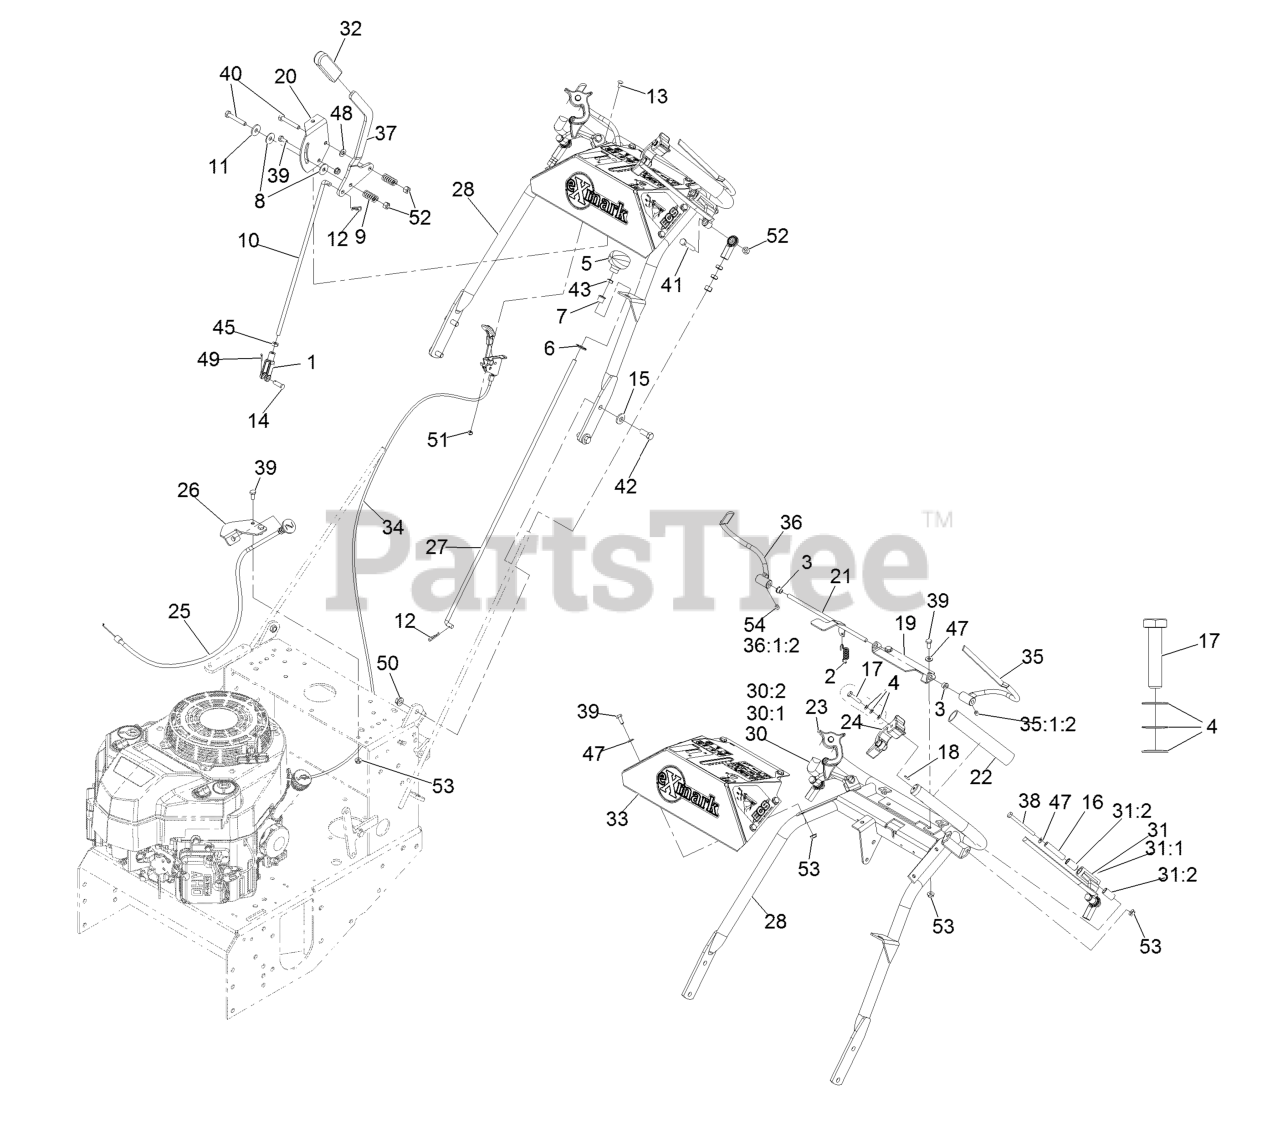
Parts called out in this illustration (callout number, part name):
1	Yoke-Adjustable
2	Spring-Extension
3	Bushing-Nylon
4	Washer-Spring Disc 1/4
5	Knob-Push / Pull
6	Nut-Push 1/2
7	Bearing-Nylon
8	Washer-Friction
9	Spring-Compression
10	Rod-Control, Speed
11	Washer-Friction Disc
12	Hairpin-Cotter
13	Bolt-Carriage #10-24 X 1/2
14	Pin-Clevis 5/16 X 1 49/64
15	Washer-Spring Disc 3/8
16	Bushing-Lever, Drive
17	Screw-HH 1/4-20 X 1 1/8 W/Nylon
18	Pin-Spring
19	Bracket, Opc Axle
20	Bracket,Shifter Slide
21	Rod Weldment, OPC
22	Grip-Bar, Handle
23	Thumb Latch Asm RH
24	Thumb Latch Asm LH
25	Cable-Choke
26	Bracket-Cable, Choke
27	Link, Blade Engagement
28	Handle Wld, Upper Ecs
30	Asm, Drive Lever RH
30:1	Wld,RH Drive Lever
30:2	Bushing, Sleeve
31	Asm, Drive Lever LH
31:1	Wld,LH Drive Lever
31:2	Bushing, Sleeve
32	Grip-Handle, Steering
33	Asm, Console W/Decals
34	Control, Throttle
35	Wld,LH OPC Lever
35:1:2	Setscrew-5/16-24 X 5/16
36	Wld,RH OPC Lever
36:1:2	Setscrew-5/16-24 X 5/16
37	Lever-Shift
38	Screw-HH 1/4-20 X 2 3/4
39	Screw-HH 1/4-20 X 5/8
40	Screw-HH 5/16-18 X 2
41	Screw-HH 5/16-18 X 1 3/4
42	Screw-HH 3/8-16 X 1
43	Nut-Jam 5/16-18
45	Nut-Jam 5/16-24
47	Washer-1/4 SAE
48	Washer-5/16 SAE
49	Pin-Cotter 3/32 X 1/2
50	Nut-Whizlock 3/8-16
51	Nut-Nyloc #10-24
52	Nut-Nyloc 5/16-18
53	Nut-Whizlock 1/4-20
54	Setscrew-5/16-24 X 5/16
